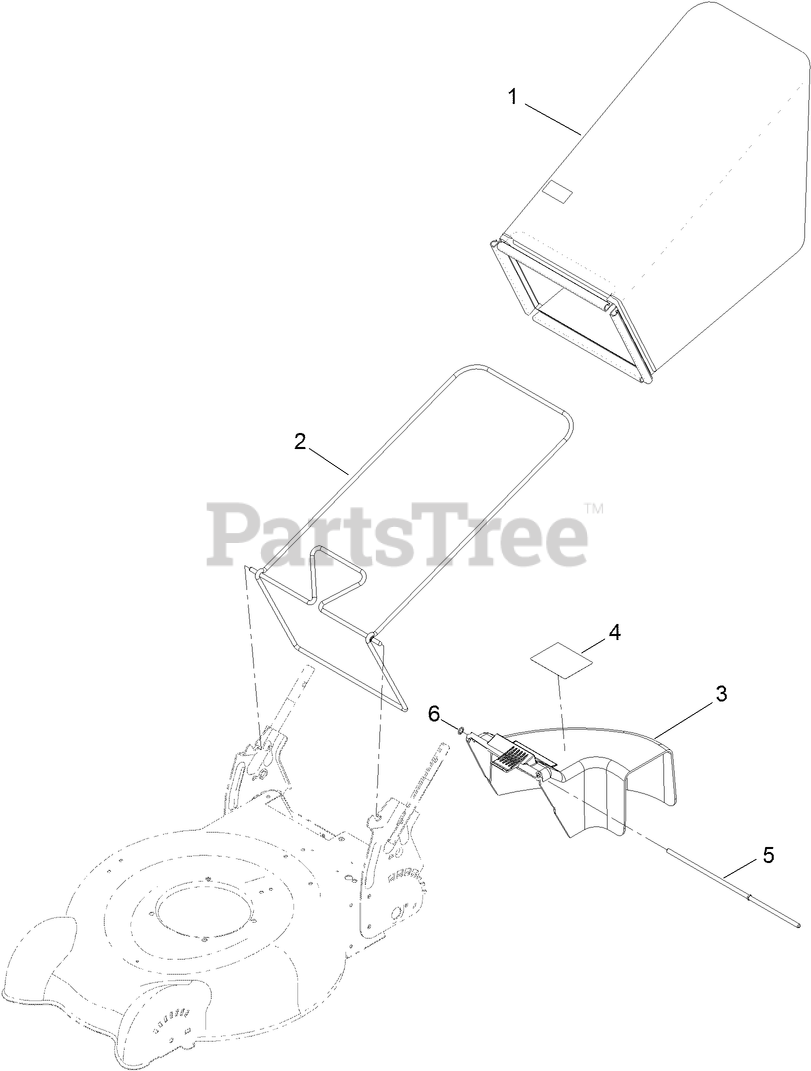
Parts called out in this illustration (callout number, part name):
1	GRASS BAG ASM
2	FRAME-BAG
3	REAR DEFLECTOR ASM
4	DECAL-WARNING
6	RING-RETAINING
